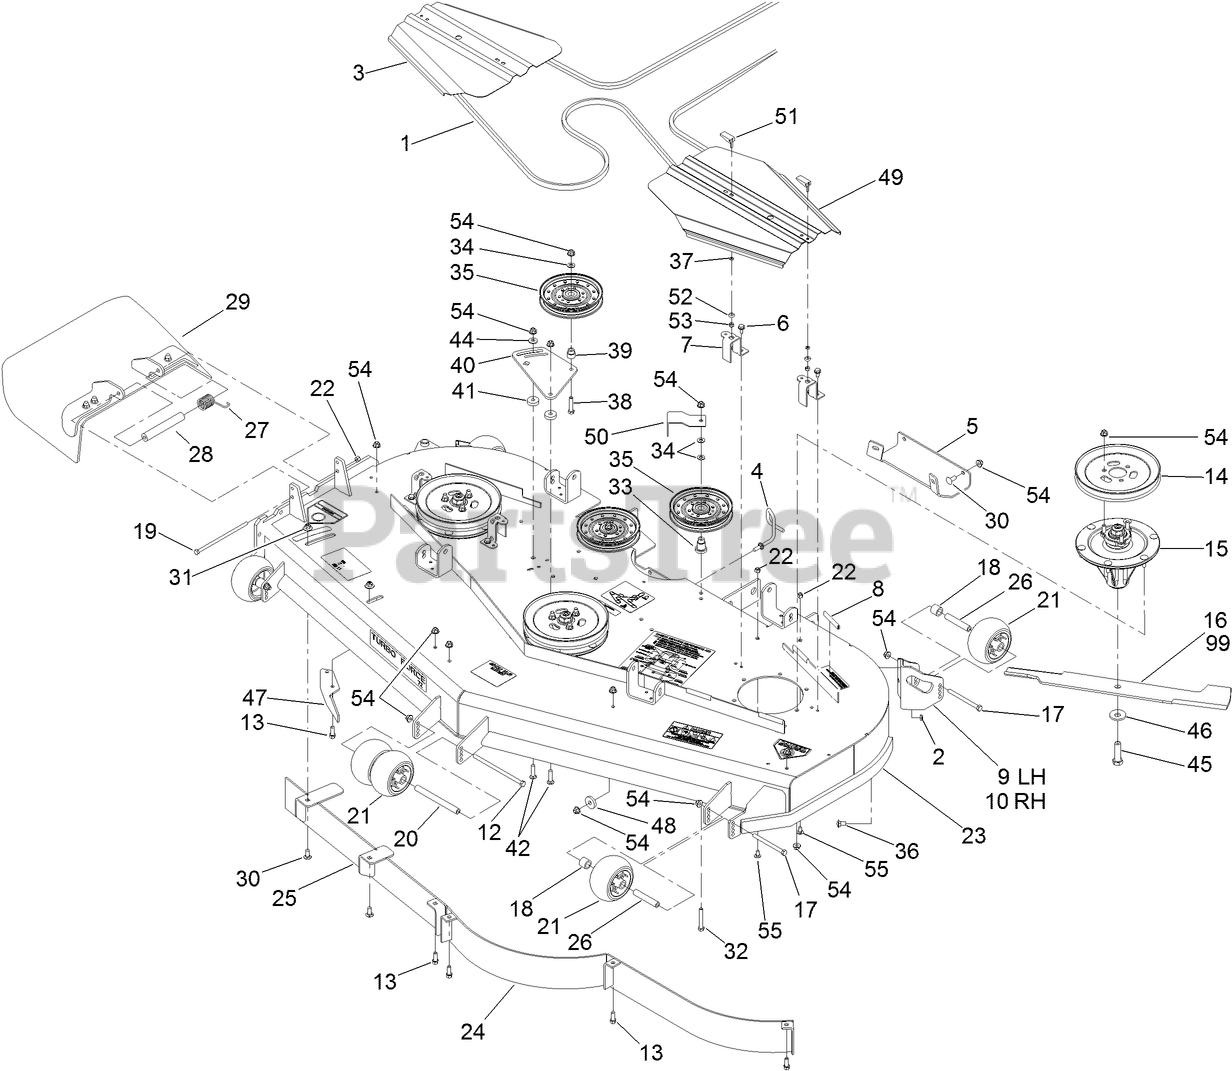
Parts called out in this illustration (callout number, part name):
2	NUT-LOCK, NI
3	COVER-BELT, RH
4	GUIDE-BELT
5	Plate-Skid
6	SCREW-HWHTF
7	BRACKET-COVER
8	STRIP-SEAL
9	MOUNT-WHEEL, LH
10	MOUNT-WHEEL, RH
12	SCREW-HH
13	SCREW-HWH
14	Pulley
15	SPINDLE ASM
16	BLADE-HI FLOW, 24.5 INCH
17	SCREW-HH
18	TUBE-SPACER
19	SCREW-HH
20	SPACER-WHEEL
21	ROLLER-SCALP, ANTI
22	NUT-LOCK, NI
23	DECK DECAL ASM
26	TUBE-SPANNER
27	SPRING-TORSION
28	SPACER
29	RUBBER DEFLECTOR ASM
30	SCREW-CARR
31	NUT-FLANGE, NI
32	SCREW-HH
33	MOUNT-PULLEY
34	WASHER-FLAT
35	Idler-Flat
36	SCREW-CARR
37	WASHER
38	SCREW-HH
39	BUSHING-IDLER
40	Plate-Idler
41	Spacer
42	SCREW-CARR
44	WASHER-BELLEVILLE
45	SCREW-BLADE
46	Washer-Blade Bolt, Heavy
47	BAFFLE-DISCHARGE
48	WASHER
49	COVER-BELT, LH
50	GUIDE-BELT
51	HANDLE-LATCH, SWELL
52	BUSHING-LATCH, SWELL
53	NUT-LOCK, HH
54	NUT-HF, NI
55	SCREW-CARR
99	BLADE-MID FLOW, 24.5IN
99	BLADE-LO FLOW, 24.5IN
99	BLADE-ATOMIC, 24.5IN
99	BLADE-RECYCLER, 24.5IN
